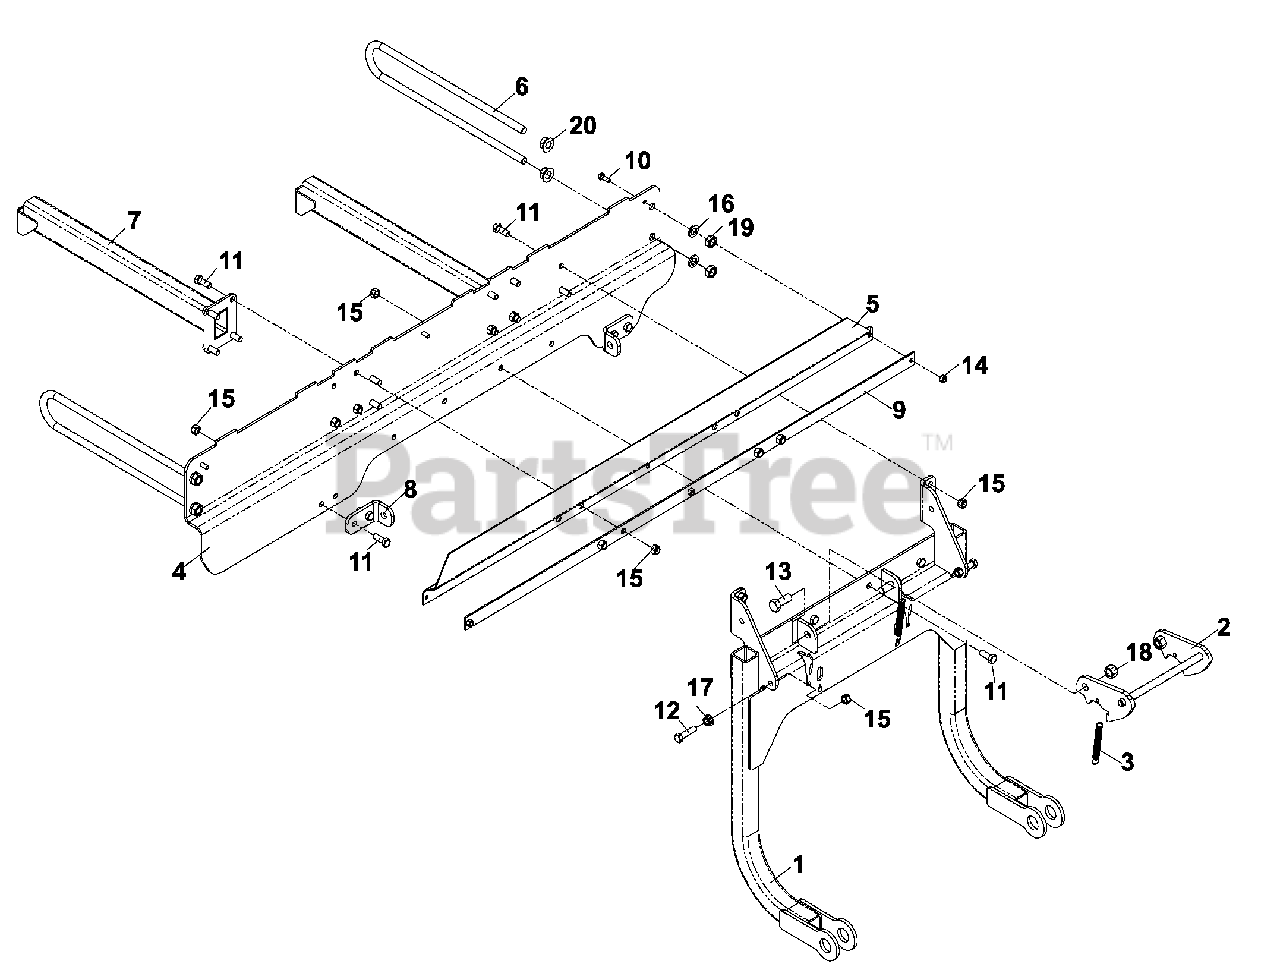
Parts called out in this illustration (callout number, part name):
4	MOUNT Z BRACE
5	SEAL, RUBBER
6	SUPPORT, OUTER
7	SUPPORT ARM
8	BRACKET, SUPPORT
9	SEAL STRAP
10	HCS, 1/4-20 X 3/4
11	HCS, 3/8-16 X 1
12	HCS, 3/8-16 X 1 1/2
13	HCS, 1/2-13 X 1 1/4
14	NUT, 1/4C, NYLOC
15	NUT, 3/8C, NYLOC
16	WASHER, 1/2
18	NUT, 1/2C, NYLOC
19	NUT, 1/2, JAM
20	NUT, 1/2-13, WHIZLOCK
